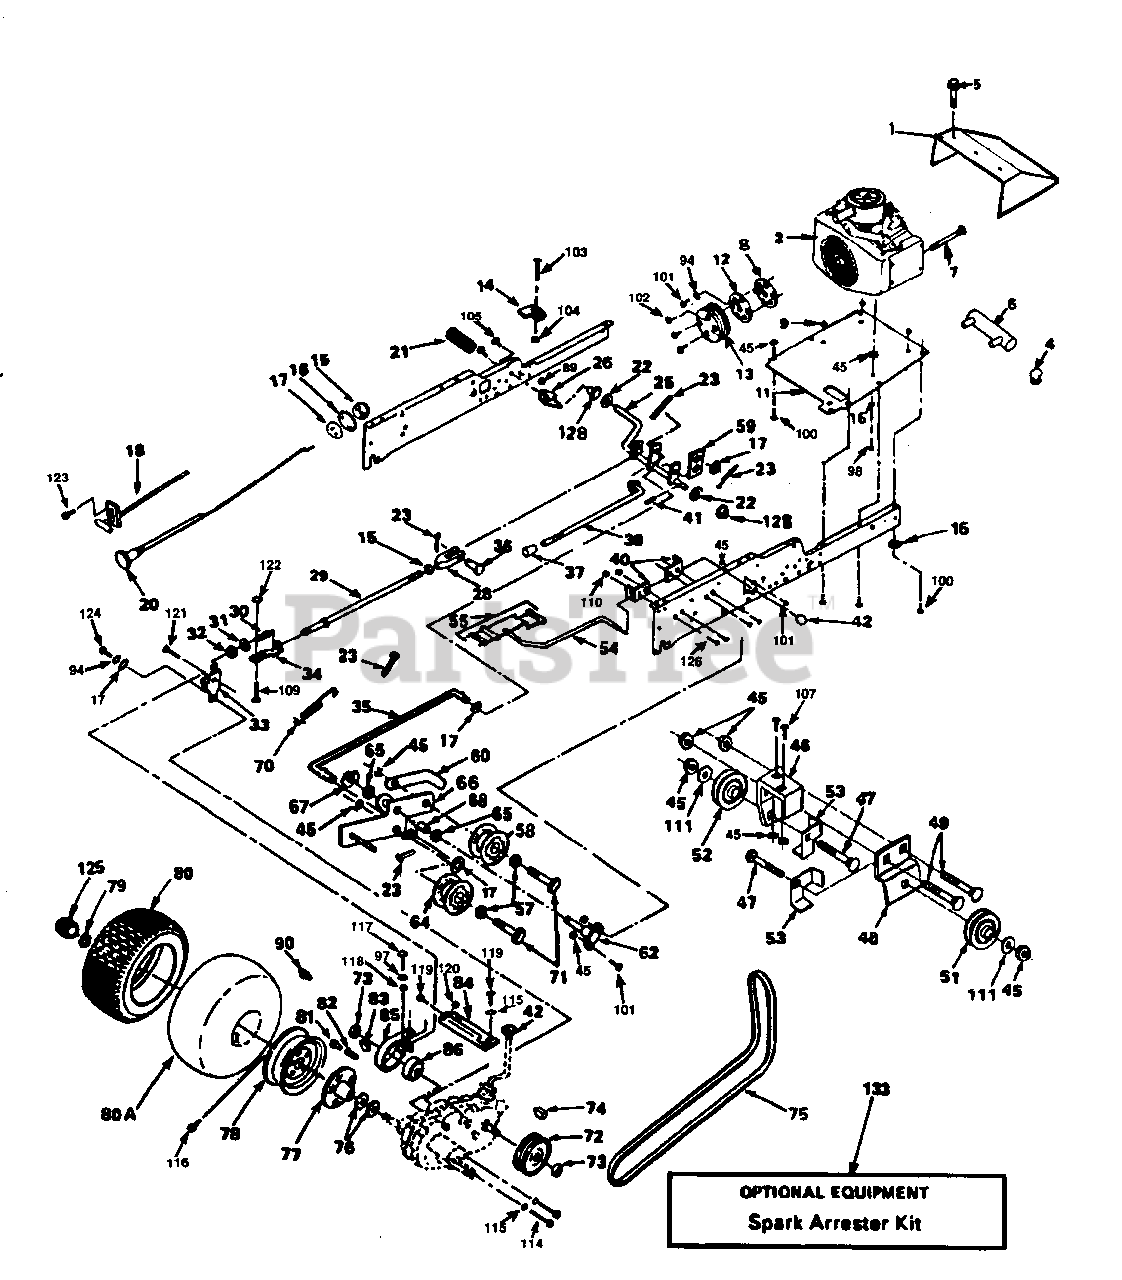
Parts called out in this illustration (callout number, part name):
1	Heat Shield
2	18 H.P. Engine
4	Exhaust Pipe
5	Thd. Cut. Hex. Screw (AYP part number)
6	Exhaust Muffler
7	Oil Drain Valve (AYP part number)
8	Chaff Guard (AYP part number)
9	Spacer (AYP part number)
11	Engine Base (AYP part number)
12	Adapter (AYP part number)
13	Ground Drive Pulley (AYP part number)
14	Interlock Switch Actuator (AYP part number)
15	Hex Nut (AYP part number)
16	Ext. Tooth Lock Washer (AYP part number)
17	Washer (AYP part number)
18	Throttle Control (AYP part number)
20	Choke Control (AYP part number)
21	Pedal Cover (AYP part number)
22	Washer (AYP part number)
23	Cotter Pin (AYP part number)
25	Foot Pedal Shaft (AYP part number)
26	Interlock Bracket (AYP part number)
28	Yoke (AYP part number)
29	Brake Rod (AYP part number)
30	Compression Spring (AYP part number)
31	Washer (AYP part number)
32	Locknut (AYP part number)
33	Brake Bracket (AYP part number)
34	Brake Rod Guide (AYP part number)
35	Clutch Rod (AYP part number)
36	Clevis Pin (AYP part number)
37	Plunger Cap (AYP part number)
39	Parking Brake Rod (AYP part number)
40	Shift Rod Bracket (AYP part number)
41	Roll Pin (AYP part number)
42	Knob (AYP part number)
45	Locknut
46	Mule Drive V-Pulley Bracket (AYP part number)
47	Carriage Bolt (AYP part number)
48	Flat Idler Bracket (AYP part number)
49	Carriage Bolt (AYP part number)
51	Flat Idler (AYP part number)
52	Idler Pulley (AYP part number)
53	Belt Keeper (AYP part number)
54	Hi-Lo Shift Rod (AYP part number)
55	Spring Clip Connecting Link (AYP part number)
57	Washer (AYP part number)
58	Flat Idler (AYP part number)
59	Spring Retainer (AYP part number)
60	Belt Retainer (AYP part number)
62	Clutch Bracket Assembly (AYP part number)
64	Grooved Idler (AYP part number)
65	Hardened Washer (AYP part number)
66	Clutch w/Bearing Bracket (AYP part number)
67	Klip Ring (AYP part number)
68	Idler Bearing (AYP part number)
70	Extension Spring (AYP part number)
71	Hex Bolt (AYP part number)
72	Transaxle Pulley (AYP part number)
73	Locknut (AYP part number)
74	Woodruff Key (AYP part number)
75	V-Belt (AYP part number)
76	Axle Thrust Washer (AYP part number)
77	Bushing Assembly and Wheel Hub (AYP part number)
78	Rear Rim Assembly (AYP part number)
79	Ring Klip (AYP part number)
80	Rear Tire (AYP part number)
80A	Rear Tube (AYP part number)
81	Valve Cap (AYP part number)
82	Valve Stem (AYP part number)
83	Woodruff No. 9 Key (AYP part number)
84	Transaxle Support Bracket (AYP part number)
85	Brake Band (AYP part number)
86	Brake Drum (AYP part number)
89	Crownlock Nut (AYP part number)
90	Grease Fitting (AYP part number)
94	Lock Washer (AYP part number)
97	Lock Washer (AYP part number)
98	Hex Bolt 3/8-16 x 1-1/4 Gr. 5 (AYP part number)
100	Hex Bolt (AYP part number)
101	Hex Bolt 3/8-16 x 1 Gr. 5 (AYP part number)
102	Hex Screw (AYP part number)
103	Fin Screw (AYP part number)
104	Locknut (AYP part number)
105	Hex Bolt (AYP part number)
107	Carriage Bolt (AYP part number)
109	Carriage Bolt (AYP part number)
110	Locknut
111	Washer (AYP part number)
114	Hex Bolt (AYP part number)
115	Lock Washer (AYP part number)
116	Hub Bolt (AYP part number)
117	Carriage Bolt (AYP part number)
118	Hex Nut (AYP part number)
119	Hex Bolt (AYP part number)
120	Crownlock Nut (AYP part number)
121	Mach. Udrcut. Flat Head Screw (AYP part number)
122	Locknut (AYP part number)
123	Hex Screw (AYP part number)
124	Hex Bolt (AYP part number)
125	Rear Hub Cap (AYP part number)
126	Carriage Bolt
128	Nyliner (AYP part number)
133	Spark Arrester Kit (AYP part number)
